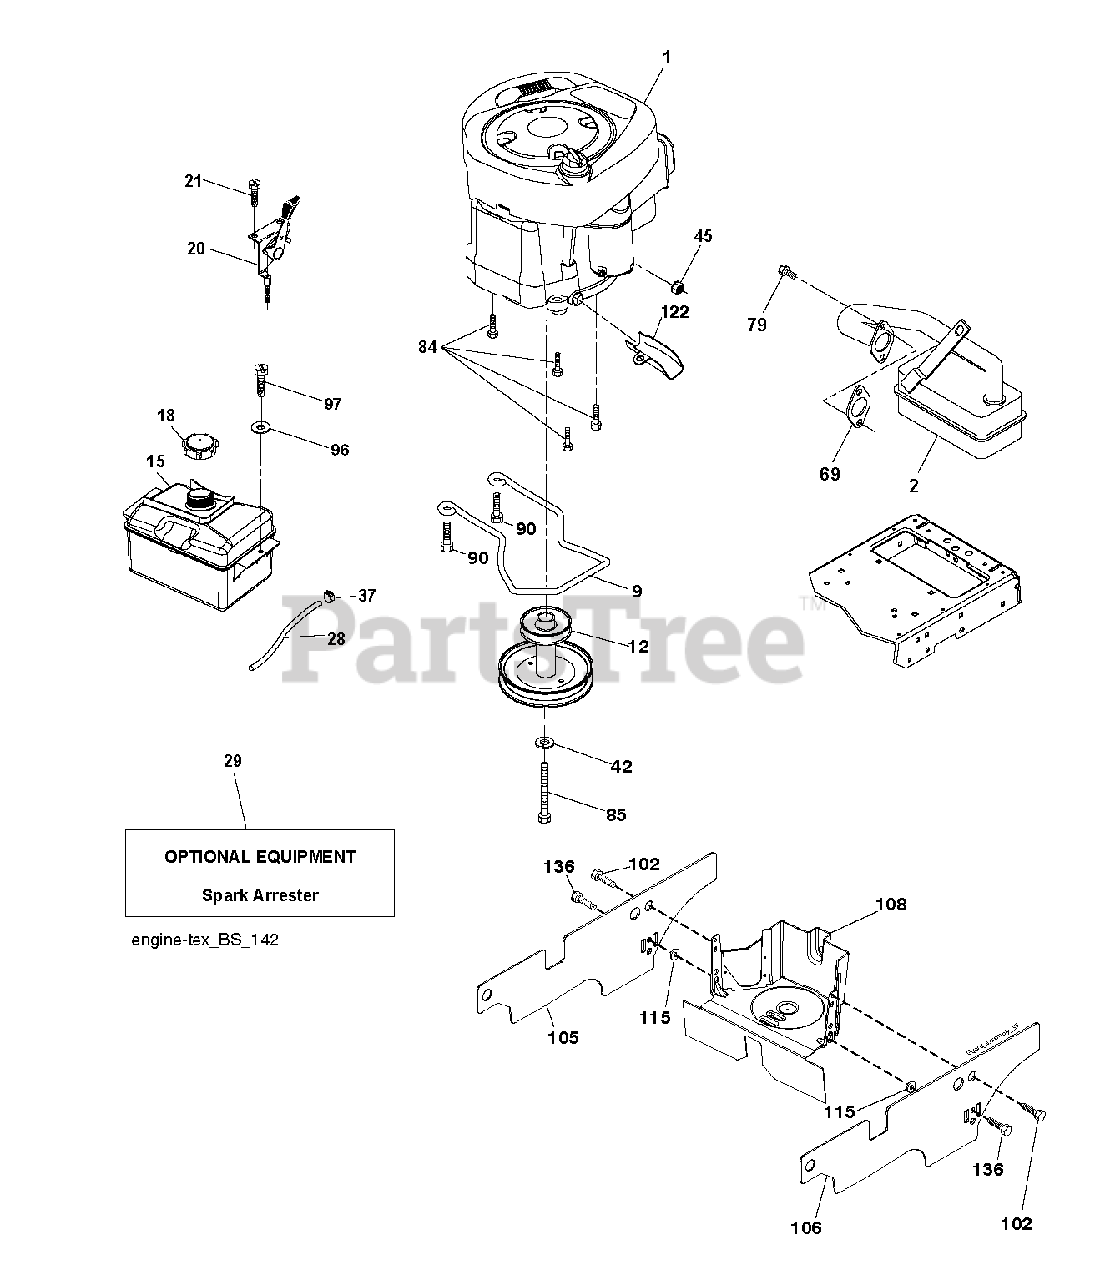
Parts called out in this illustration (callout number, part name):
2	MUFFLER.B&S.MODEL.21.11HP.OHV
9	KEEPER.BELT.ENG.3.25"2BOLT.PNT
12	PULLEY.ENGINE
15	RP TANK FUEL FRT 1.5 GAL
18	CAP ASM.FUEL.2.25"FR.
20	CONTROL.TH/CK.C.
21	SCREW.#10 X 0.750.BOS
28	LINE.FUEL.20
29	KIT.SPARK ARRESTOR 794945 B&S
37	HOSE CLAMP
42	WASHER 7/16 LOCK
45	NUT
69	GASKET.EXHAUST.KOHLER
79	SCREW.SOCKET HD.5/16-1
84	SCREW.3/8-16
85	BOLT.HEX.7/16-20X4.GR5.1.5BLUE
90	SCREW 3/8-16X1
97	SCREW HEXWSHR 1/4-20X3/4
102	SCREW
105	SHIELD.SIDE.LH.3842"TEX FRN.BK
106	SHIELD.SIDE.LH.3842"TEX FRN.BK
108	COVER.PULLEY.ENG.WSHL
122	EXTENSION DRAIN OIL
136	SCREW.#10 X 0.500
